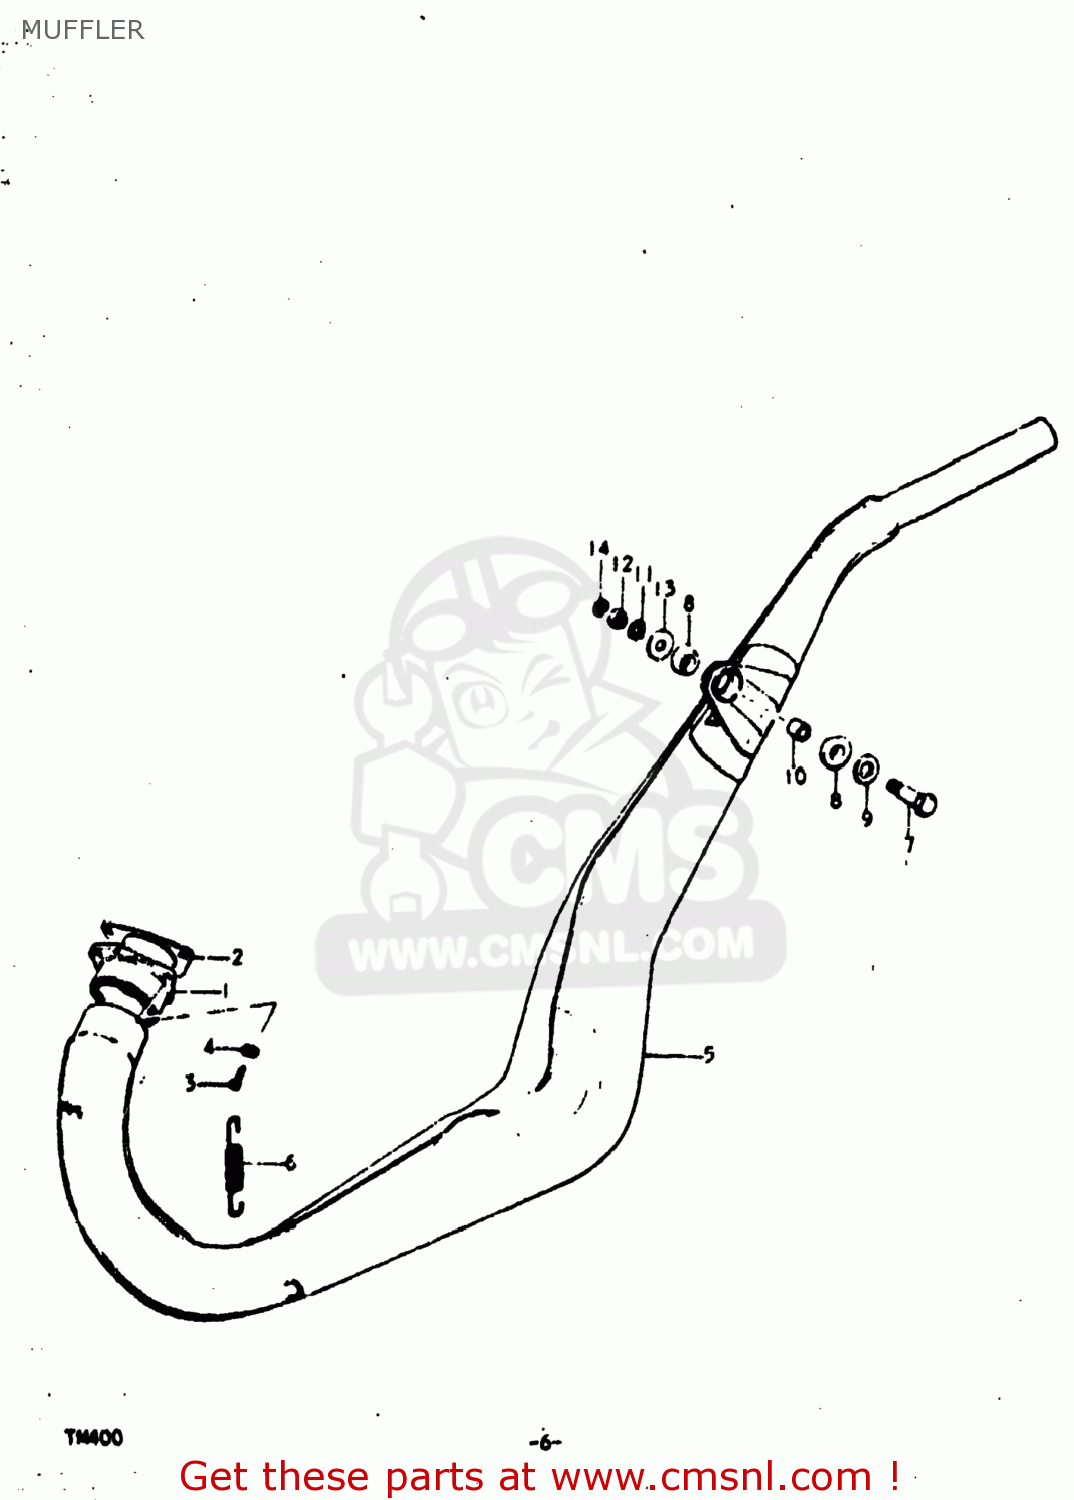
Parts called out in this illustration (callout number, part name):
1	FLANGE,EXHAUST PIPE
2	GASKET,EXHAUST PIPE (MCA)
3	SCREW
4	LOCK WASHER
5	BODY,MUFFLER
6	MUFFLER ASSEMBLY
7	PIPE,MUFFLER BAFFLE
8	LOCK WASHER
9	SCREW(6X8)
10	SPRING
11	CONNECTOR,MUFFLER
12	CLAMP
13	SCREW
14	BRACE,MUFFLER
15	BOLT 8X40
16	CUSHION
17	SPACER (8.2X12.5X23.5)
18	WASHER (8.7X22X2)
19	LOCK WASHER
20	BOLT
21	WASHER
22	LOCK WASHER
23	SPRING
24	BOLT
25	CUSHION
26	WASHER (8.7X22X2)
27	SPACER (8.2X12.5X23.5)
28	NUT L,M
29	WASHER
30	WASHER 6MM
31	E RING 6MM
32	LOCK WASHER
